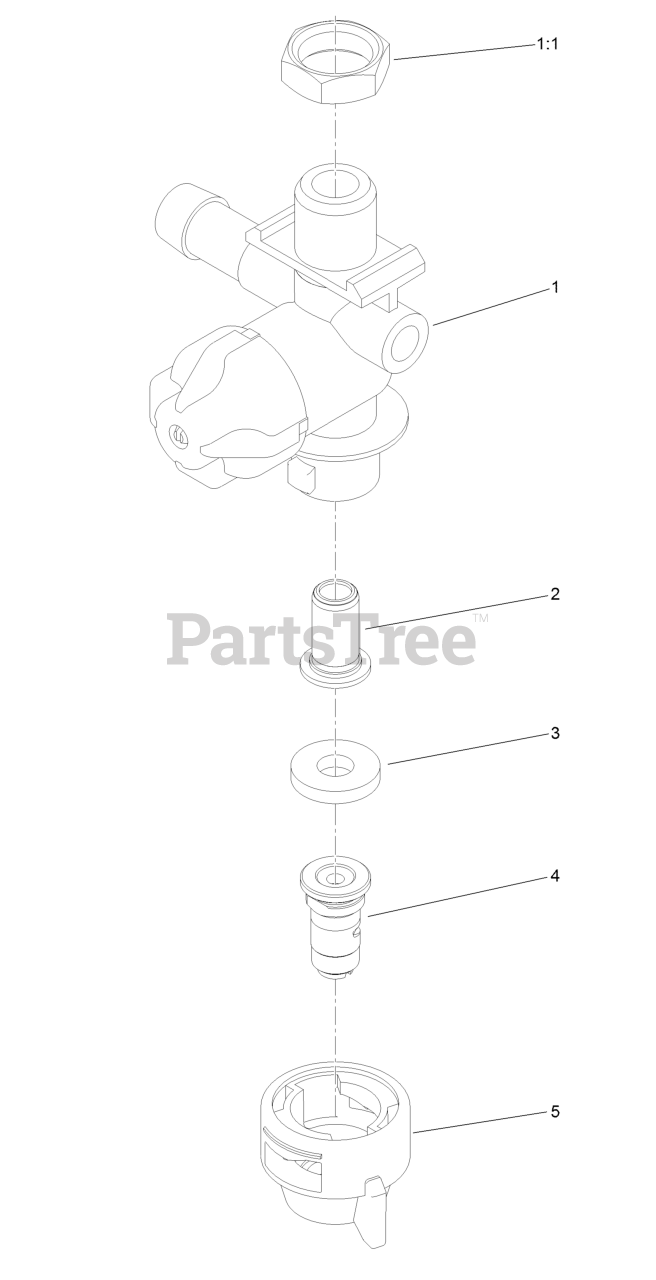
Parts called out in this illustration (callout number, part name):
1	RH Nozzle Body ASM
1:1	Nut-Nylon
2	Strainer-Tip
3	Gasket-Seal
4	Nozzle-Spray, Red
5	Cap-Nozzle
99	Nozzle-Spray, Gray
99	Nozzle-Spray, White
99	Nozzle-Spray, Brown
99	Nozzle-Spray, Blue
